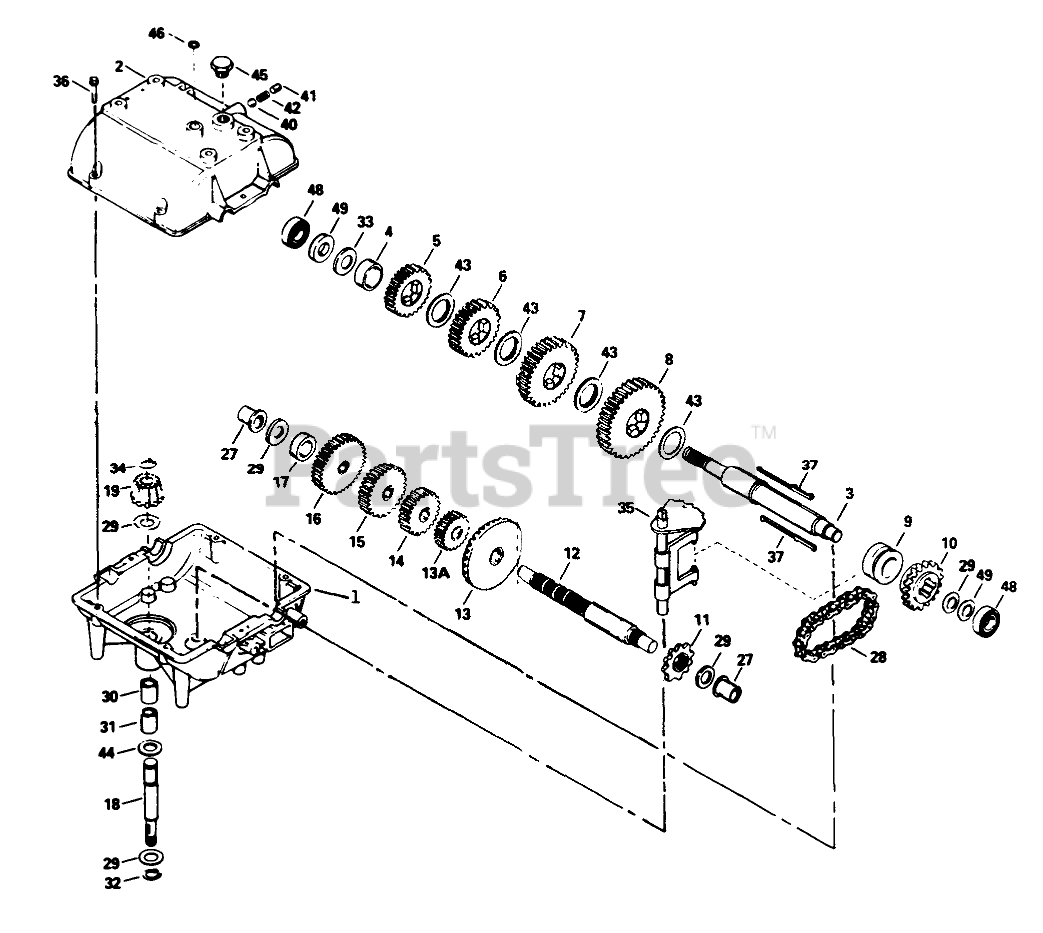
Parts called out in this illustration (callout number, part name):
1	Case-Transmission
2	Cover-Transmission
3	Shaft-Output/Brake
4	Spacer
5	Gear-Spur, 25 Teeth
6	Gear-Spur 27 Teeth
7	Gear-Spur, 30 Teeth
8	Gear-Spur, 35 Teeth
9	Collar-Shift
10	Sprocket-18 Teeth
11	Sprocket-9 Teeth
12	Countershaft
13	Gear-Bevel, 42 teeth
13A	Gear-Spur 15 Teeth
14	Gear-Spur, 20 Teeth
15	Gear-Spur 23 Teeth
16	Gear-Spur, 25 Teeth
17	Spacer
18	Shaft-Input
19	Bevel Pinion-Input
27	Bushing-Flange
28	Chain-Roller #41
29	Washer
30	Bearing-Needle
31	BeARing-Needle
32	Ring-Snap
33	Washer
34	Ring-Retainer
35	Rod and Fork ASM
36	Ring Set (.020 O S)
40	Ball-Steel
41	Screw-Set
42	Spring
43	Washer
44	O Ring
46	Cut Seal-Square
48	Bearing-Ball
49	Thrust Washer
